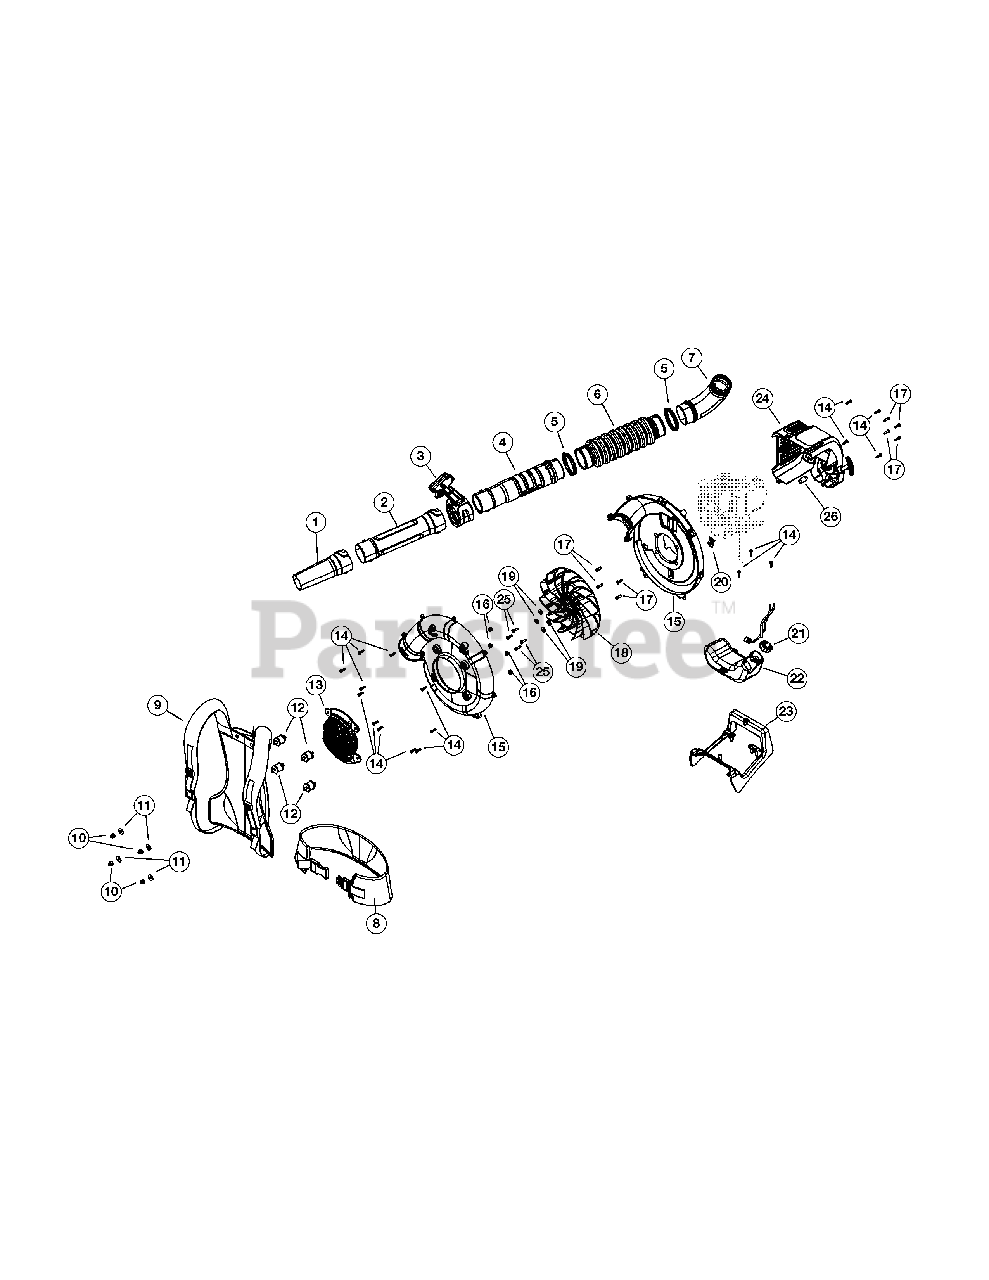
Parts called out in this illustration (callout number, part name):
1	Concentrator Nozzle
2	Lower Blower Tube
3	Throttle Grip Assembly
4	Upper Blower Tube
6	Flex Tube
7	Elbow Tube
8	Hip Belt
9	Support System
10	Nut
11	Washer
12	Isolator Mount
13	Intake Cover
15	Impeller Housing Assembly
17	Housing Screw
18	Impeller (Incl. Ref No. 19 & 25)
20	Throttle Retaining Clip
21	Fuel Cap
22	Fuel Tank Assembly (Incl. Ref No. 21)
24	Engine Cover Assembly
25	Impeller Screw
26	Electric Starter Adapter
